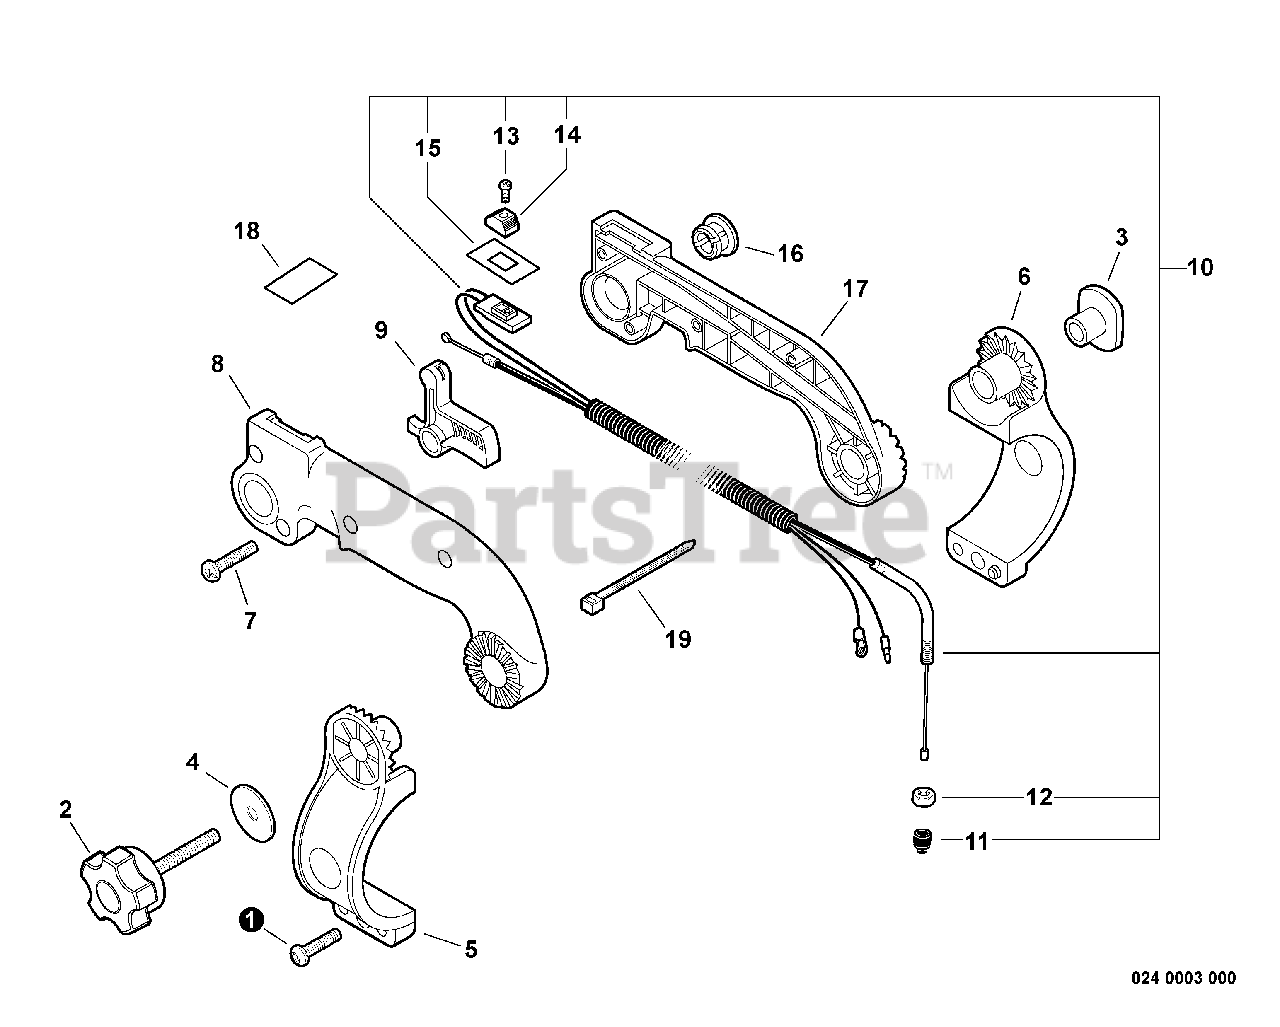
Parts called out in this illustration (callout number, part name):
1	SCREW, TAPPING 5×20
2	KNOB, SCREW
5	BRACKET, HANDLE - LEFT
6	BRACKET, HANDLE - RIGHT
7	SCREW 4×22
8	HANDLE, FRONT - LEFT
9	TRIGGER, THROTTLE
10	CONTROL CABLE ASSY
11	CAP, DUST
12	NUT, HEX M6
13	SCREW 3×10
14	KNOB, SWITCH - ORANGE
15	LABEL, SWITCH
17	CONTROL HANDLE - RIGHT
18	LABEL, CAUTION - IDLE
19	STRAP, TIE - LARGE
